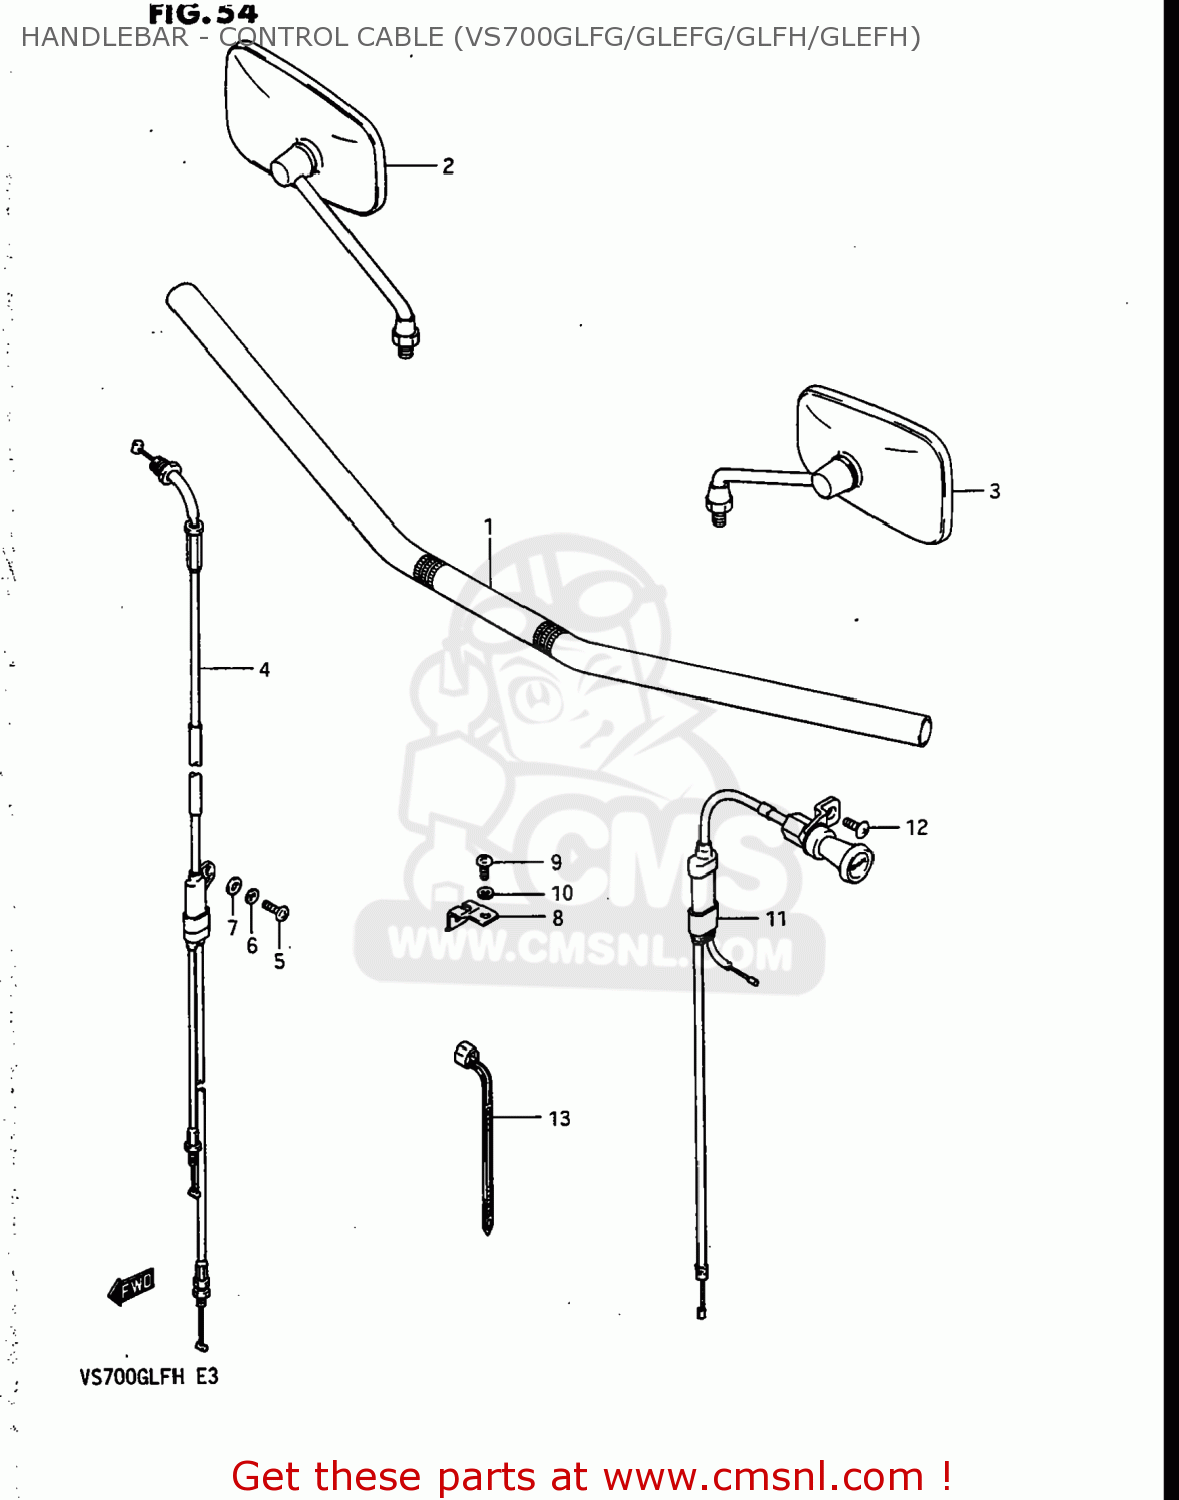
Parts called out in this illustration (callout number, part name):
1	HANDLEBAR,RIGHT
2	MIRROR ASSY,RR VIEW,R
3	MIRROR ASSY,RR VIEW,L
4	CABLE ASSEMBLY,THROTTLE
5	SCREW
6	LOCK WASHER
7	WASHER
8	CLAMP,THROTTLE CABLE
9	SCREW
10	LOCK WASHER
11	CABLE ASSEMBLY,STARTER
12	SCREW
13	CLAMP(L:125)
